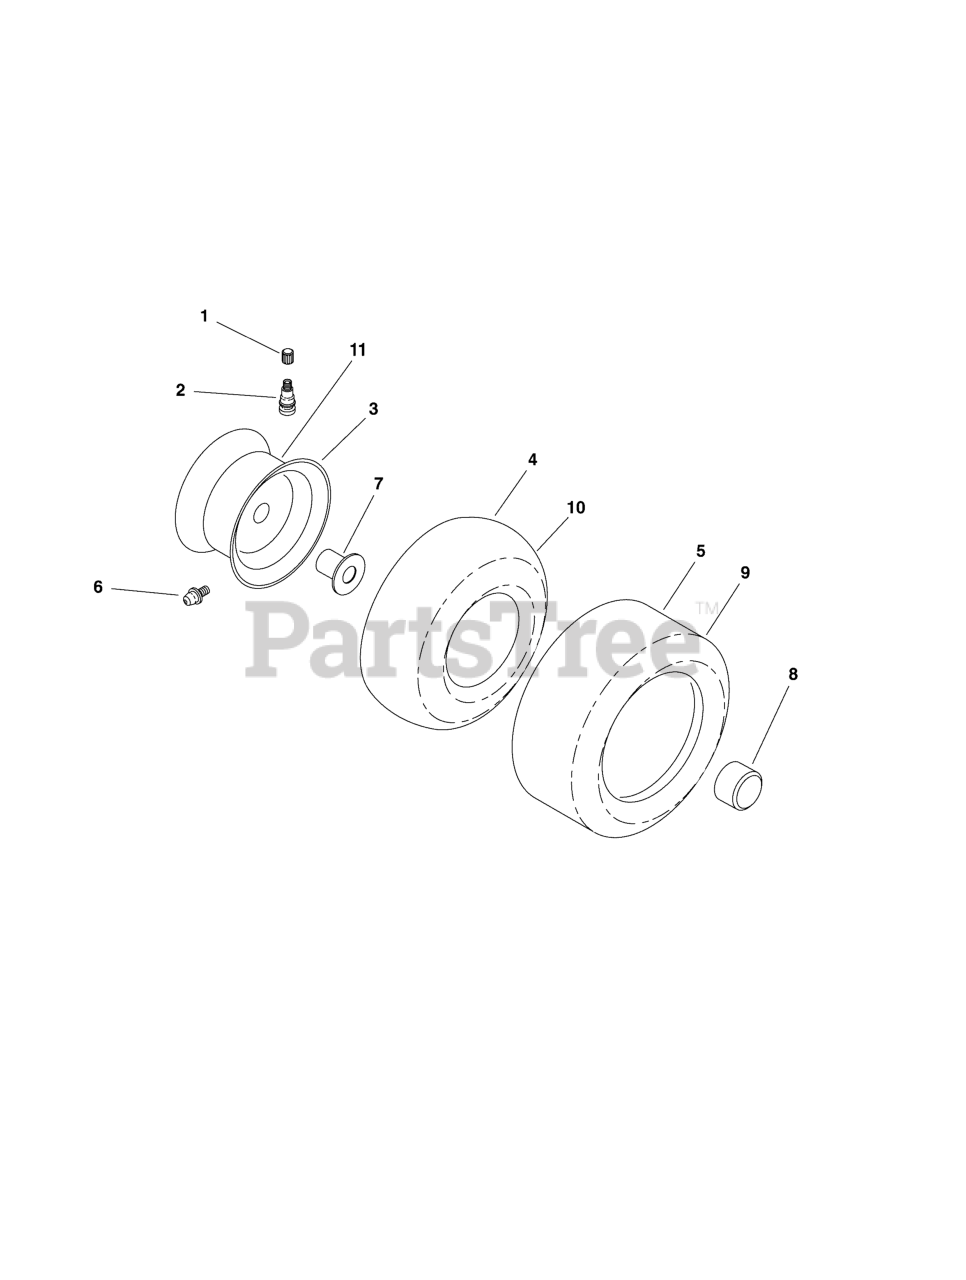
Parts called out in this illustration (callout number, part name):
1	Cap, Valve, Tire
2	Stem, Valve
3	ASSEMBLY, Front Rim
4	Tube, Front
5	TIRE, Front 15 x 6-6
6	FITTING, Grease
7	BEARING, Flange
8	Cap, Axle
9	Tire, Rear 20 x 8-8
10	Tube, Rear
11	Rim Assembly, Rear
12	SEALANT, Tire (10 oz. Tube)
